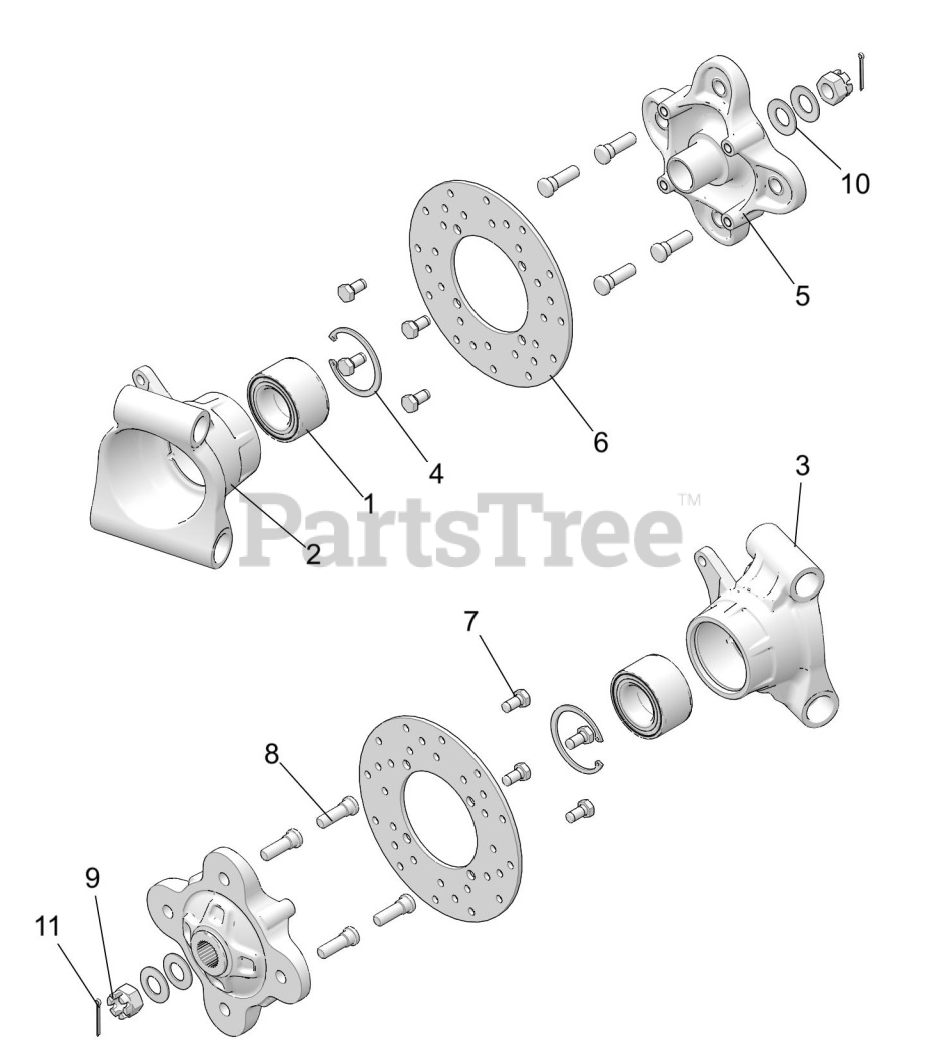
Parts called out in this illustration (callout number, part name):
1	BEARING-WHEEL-40X74X40MM
2	CARRIER-BEARING-LH
3	CARRIER-BEARING-RH
4	RING-RETAINING
5	HUB-WHEEL-MACH-BLK
6	DISC-BRAKE-REAR-8.625X.188
7	SCR-M10X1.5X20-8.8 ZY3
8	STUD-WHEEL-M12-1.5
9	NUT-M18X1.5-CASTLE-ZINC/YELLOW
10	WSHR-AXLE-M18-42X4.5
11	PIN- COTTER
